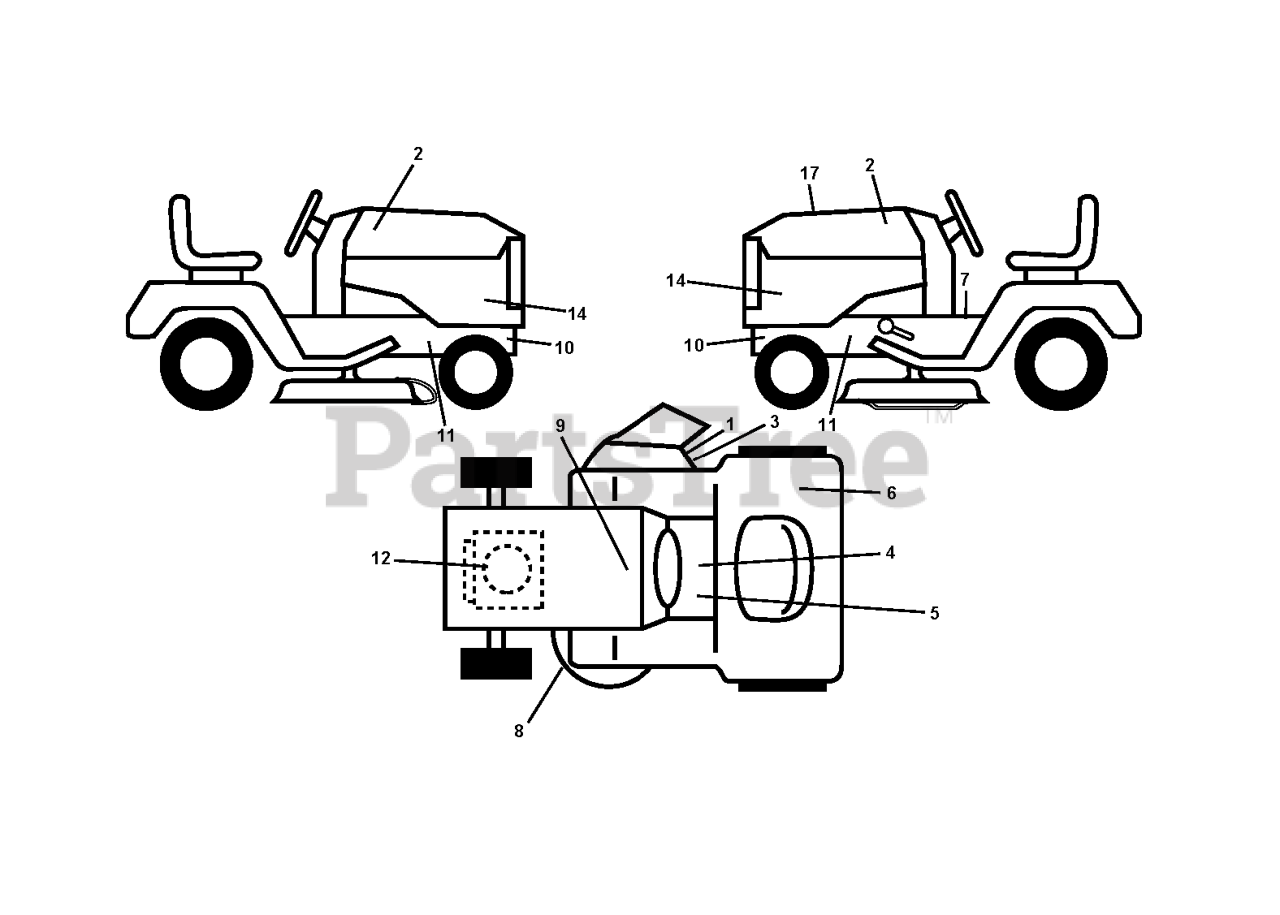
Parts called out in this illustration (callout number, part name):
1	DECAL.INTERNATIONL.CUTFINGER
2	RP.DECAL.BADGE.170MM.TEXTLOGO
3	DECAL, DEFLECT WARNING
4	DECAL PARK BRAKE
5	LABEL
6	Decal, Fender 100 DB/CE
7	DECAL
8	DECAL V BELT SCHEMATIC
9	DECAL BTRY SYMBOLS
12	DECAL
